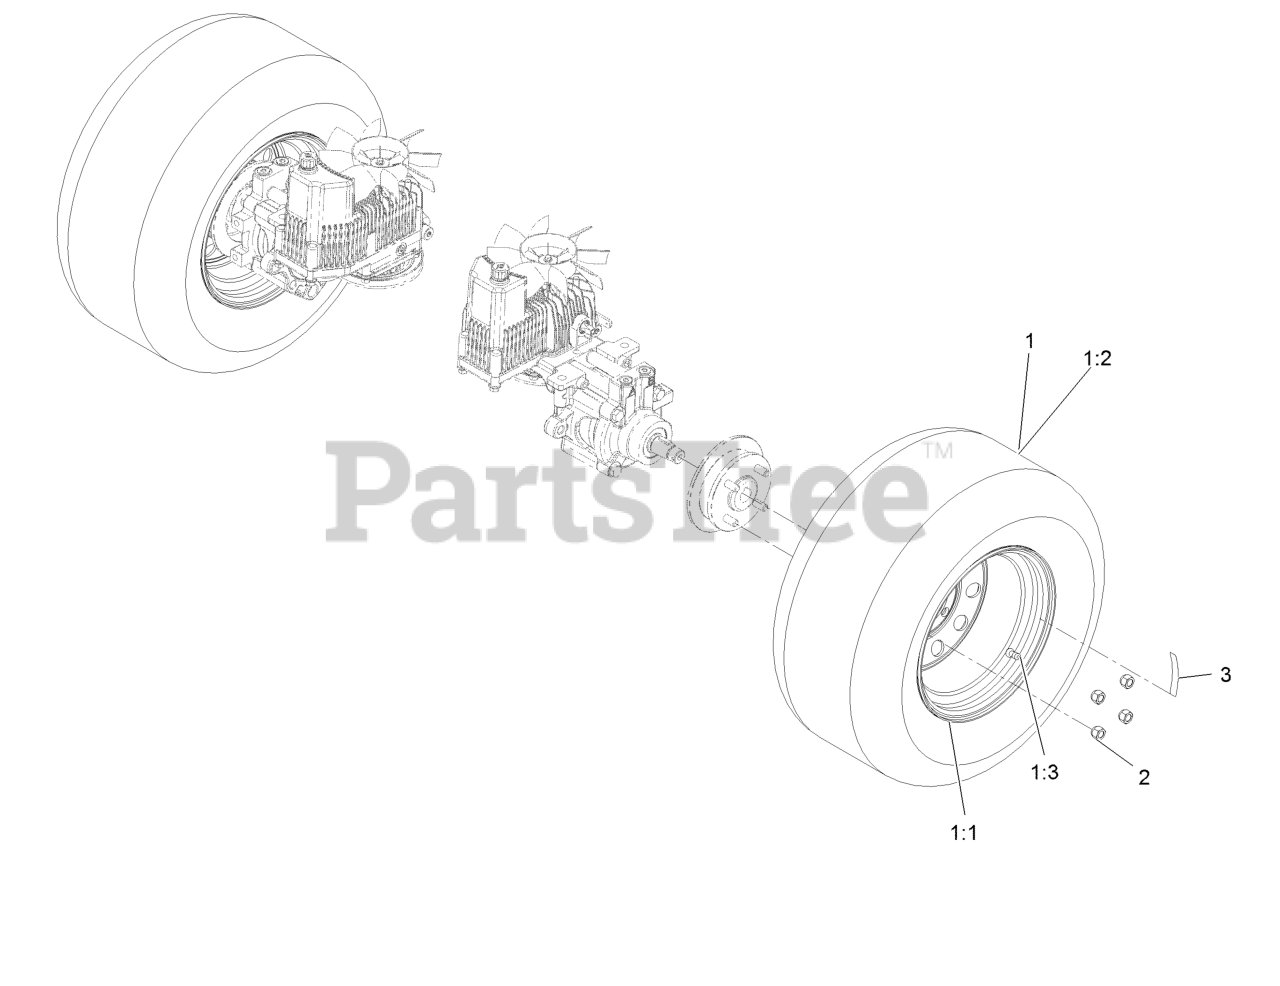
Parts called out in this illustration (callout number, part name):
1	ASM-Wheel And Tire
1:1	ASM-Rim 72
1:2	Tire-Drive
1:3	Stem-Valve
2	Nut-Lug 1/2-20
3	Decal-Torque, Wheel Hub Lug
